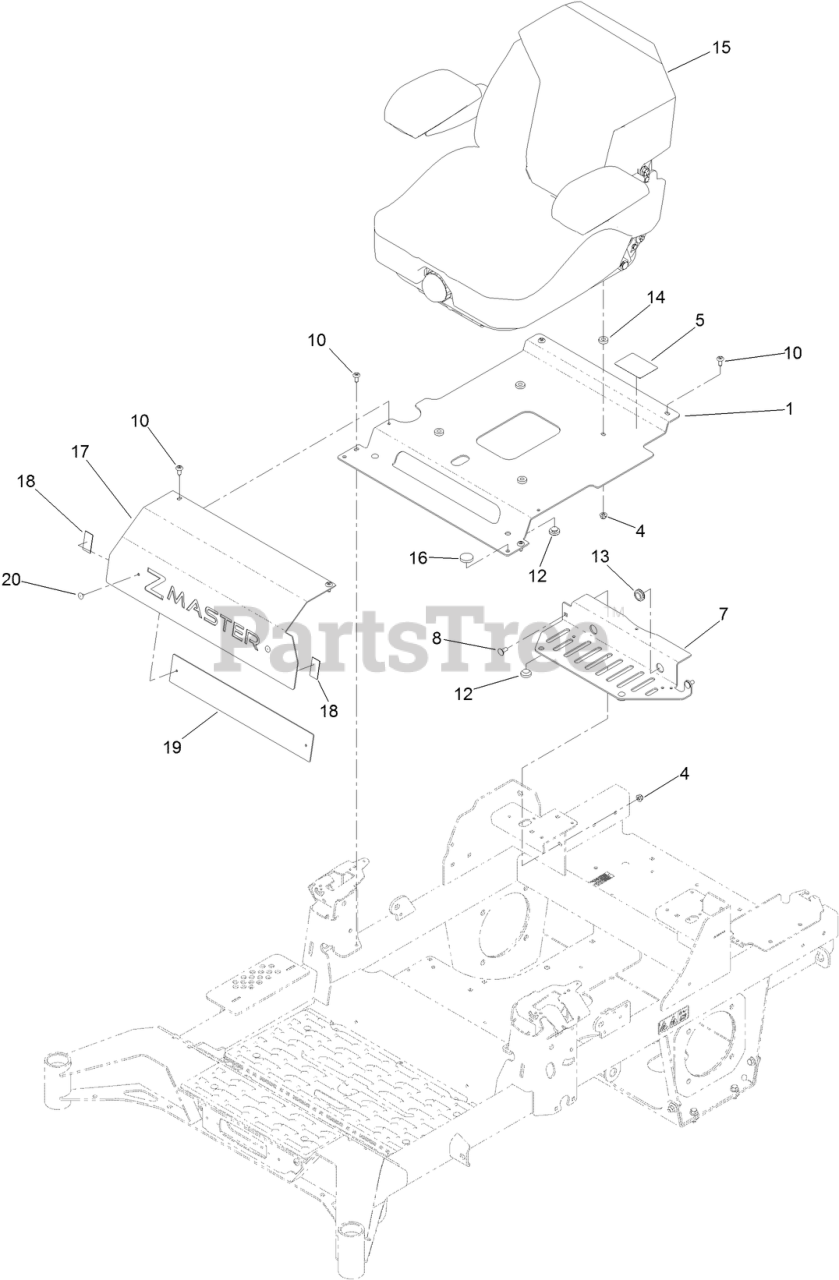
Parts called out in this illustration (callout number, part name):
1	PAN-SEAT [BLACK]
4	NUT-HF, NI
5	DECAL-SERVICE AID
7	PLATE-TANK RETAINER, REAR
8	SCREW-CARR
12	BUMPER-SEAT
13	GROMMET
14	SPACER
15	SEAT ASM-SUSPENSION
16	BUMPER-PUSH-IN, RUBBER
17	PLATE-TANK RETAINER, FRONT
18	PAD-RUBBER
19	PLATE-BACKER
20	RIVET-POP
